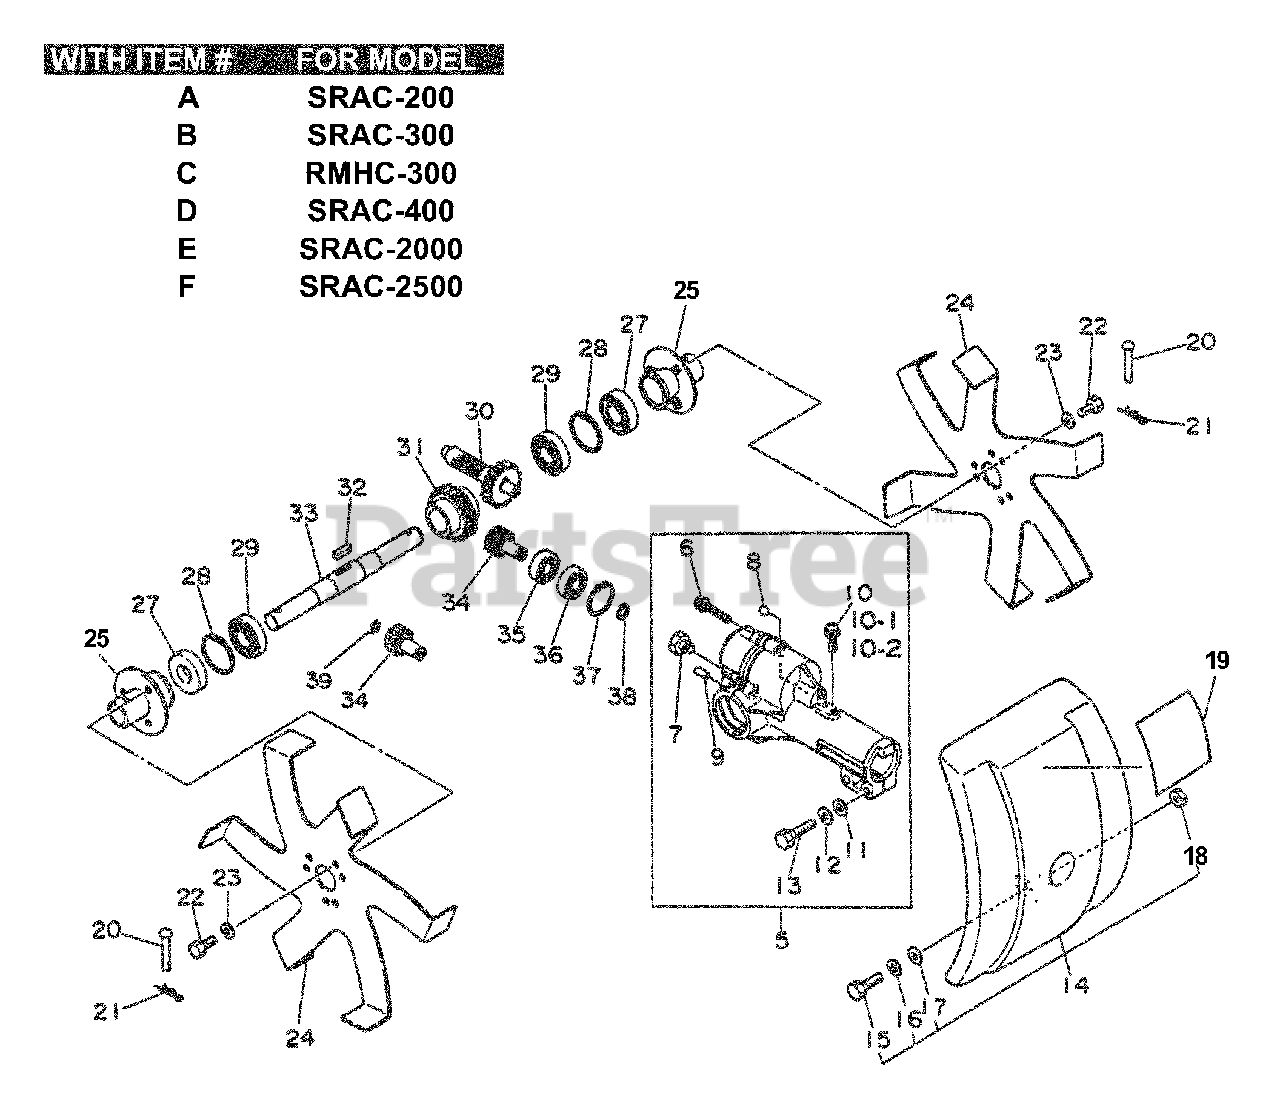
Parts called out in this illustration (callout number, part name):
5	GEAR CASE ASSY
5	CASE, GEAR
6	SCREW - 4X25
7	BOLT - 8X8
8	BALL, STEEL
9	PIN - LOCATING
10	SCREW - 5X14
10-1	LOCKWASHER - 5
10-2	WASHER - 5
11	WASHER - 6
12	LOCKWASHER - 6
13	BOLT - 6X25
14	SHIELD
15	BOLT - 6X20
16	LOCKWASHER - 6
17	WASHER - 6
18	LOCKNUT - 6
19	LABEL
20	PIN - CLEVIS
21	PIN, SPLIT
22	BOLT - 6X10
23	LOCKWASHER - 6
24	BLADE, CULTIVATOR
25	HUB, CLUTCH
27	SEAL, OIL - 17
28	RING, RETAINING - 30
29	BEARING, BALL - 6903
30	GEAR - DRIVE
31	WHEEL, WORM
33	SHAFT, WORM GEAR
34	GEAR - DRIVE
34	GEAR
35	BEARING, BALL - 609
35	BEARING, BALL - 6001
35	BEARING, BALL - 6900
36	BEARING, BALL - 609
36	BEARING, BALL - 6001Z
36	BEARING, BALL - 6900
37	RING, RETAINING - 22
37	RING, RETAINING - 28
38	RING, RETAINING - 9
38	RING, RETAINING - 12
38	RING, RETAINING - 10
39	RING, RETAINING - 7
